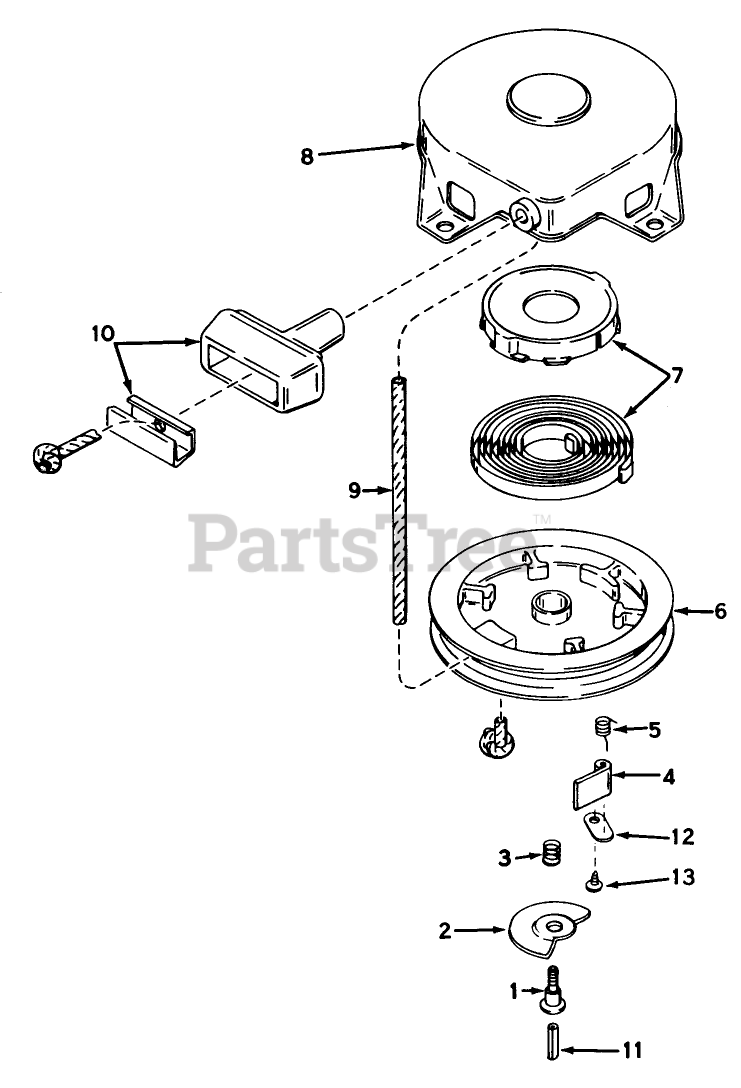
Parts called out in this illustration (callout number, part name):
1	Screw
2	Cam-Dog
3	Spring-Brake
4	Dog-Starter
5	Spring-Dog
6	Pulley
7	Spring Keeper Assy
8	STARTER HOUSING ASSY
9	Rope-Starter
10	Assy., Starter
11	Centering
12	Retainer-Dog
13	Screw
